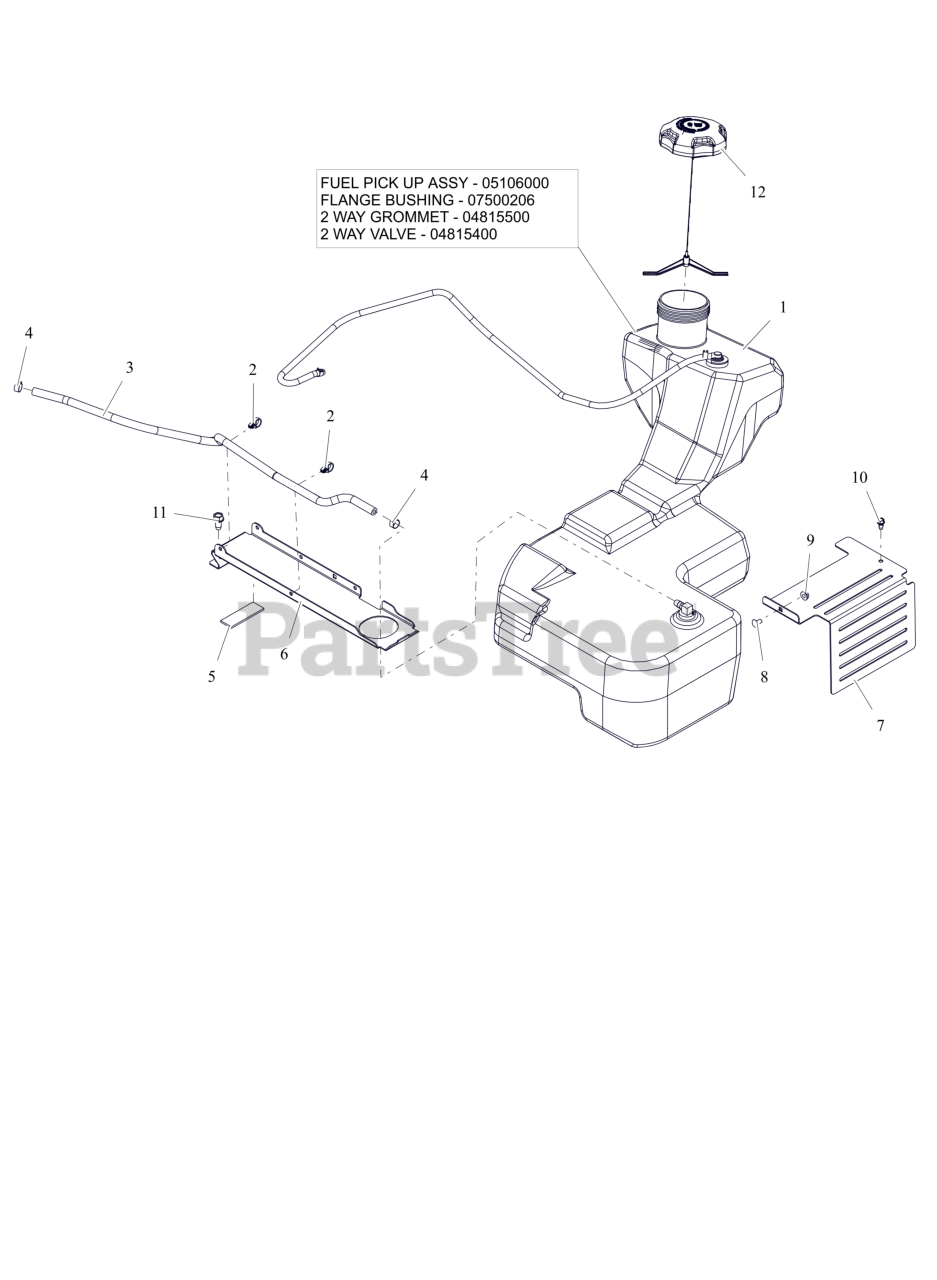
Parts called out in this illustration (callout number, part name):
1	ASM, FUEL TANK-HD
1	ASM, HD FUEL PICK-UP
1	BSHG-FLG .375X1.062X.625 NITR
1	GROMMET, 2-WAY
1	VALVE, 2-WAY
2	ROUTING CLIP (1/2" ID)
3	HOSE, .25 LOW-PERM BULK GAS
4	CLAMP, FUEL LINE
5	PAD,RBR 1.0"X3.0" W/ADHESIVE
6	BRKT, FUEL TANK HOLD DOWN
7	GUARD, TRANSAXLE FAN LH (BLACK)
8	BLT, RHSSN.25-20X.500 G5 ZCC
9	NUT-LK-CTR-FLG .25-20 ZC120
10	SCR-TAP .25-20X.50 HWH ZCC
11	SCR,TAP .375-16X.75 HWH TR ZCC
12	CAP, FUEL - 3.50 RATCHET INLET VENT
